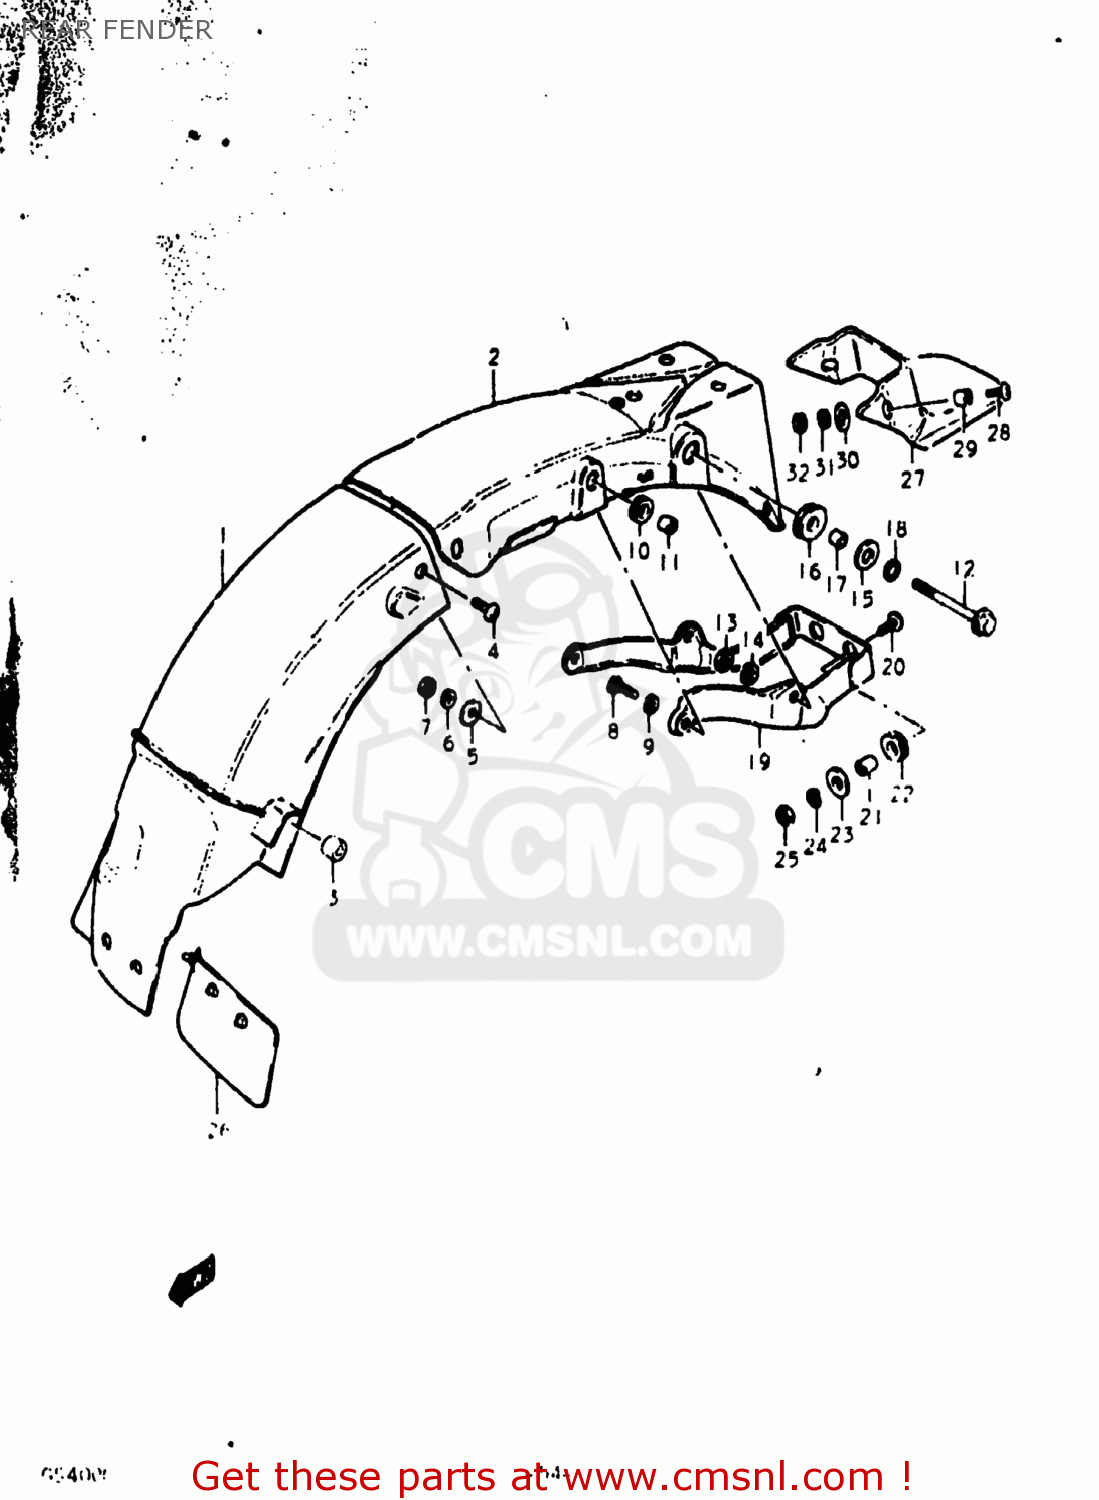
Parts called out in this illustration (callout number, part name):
1	FENDER,REAR
2	BODY,RR FENDER RR
3	CUSHION
4	SCREW
5	WASHER (5.5X16X1.2)
6	LOCK WASHER
7	NUT
8	BOLT
9	LOCK WASHER
10	CUSHION
11	SPACER(6.1X9X7.5)
12	BOLT
13	NUT
14	LOCK WASHER
15	WASHER(8.5X26X1.2)
16	CUSHION
17	SPACER (8.2X12X7.5)
18	WASHER
19	REINFORCEMENT,REAR FENDER
20	SCREW
21	SPACER (6.1X9X9)
22	CUSHION
23	WASHER(6,5X22X1.6)
24	LOCK WASHER
25	NUT
26	MUD GUARD,REAR FENDER
27	EXTENSION,REAR FENDER
28	SCREW (6X15)
29	SPACER(6.2X8.3X5.7)
30	WASHER(6.5X18X1)
31	LOCK WASHER
32	NUT
